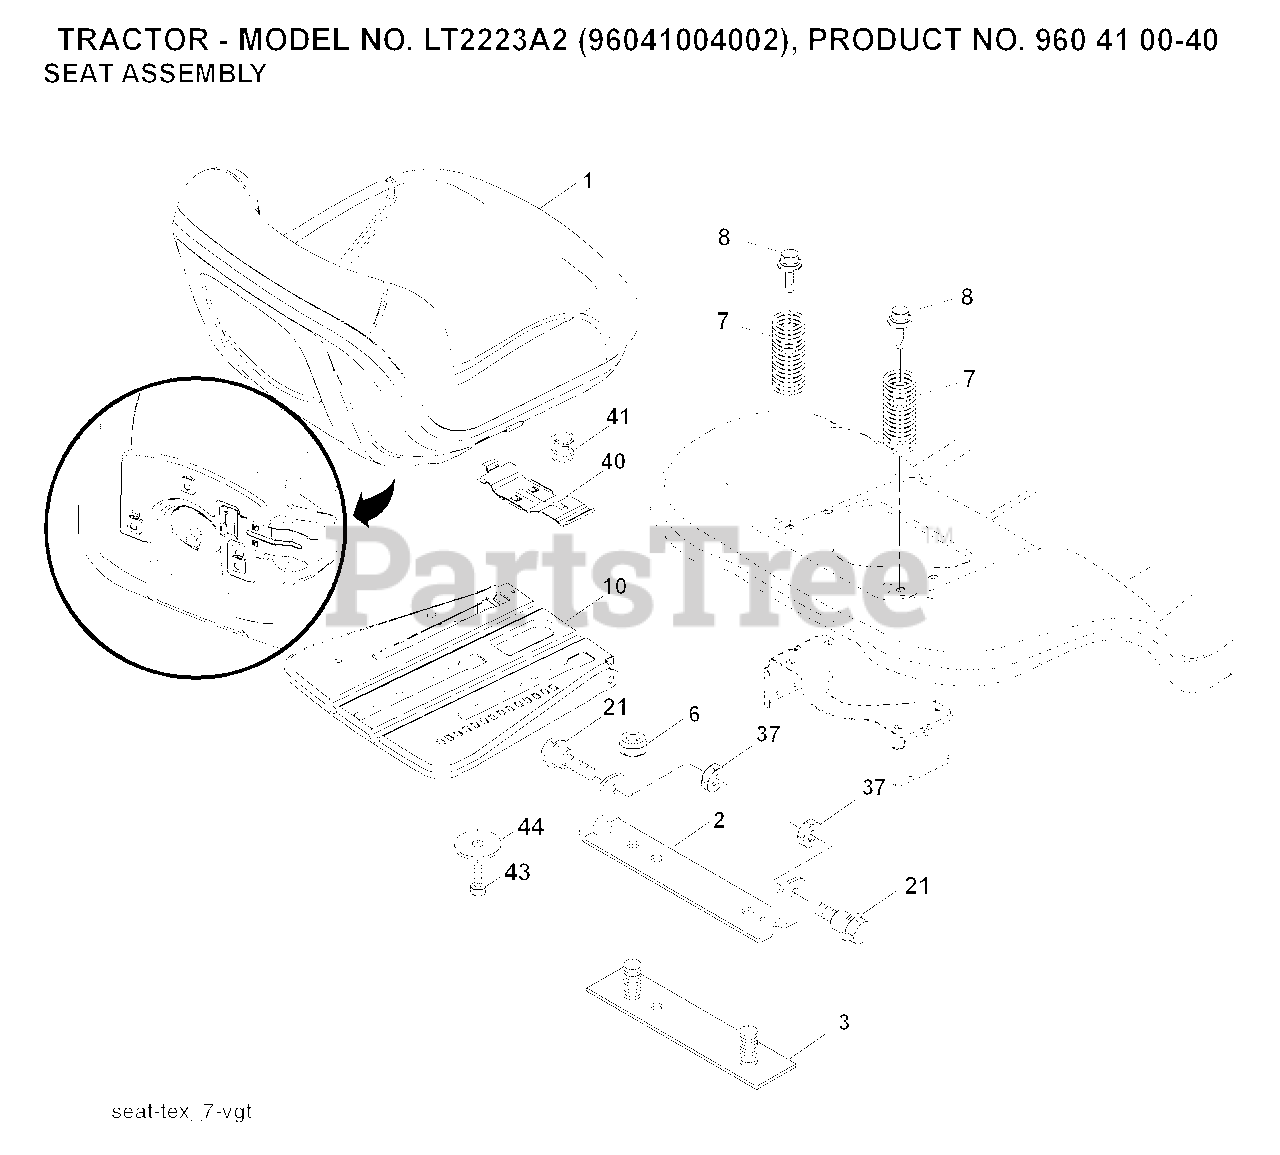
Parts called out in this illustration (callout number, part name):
1	SEAT.TG150.BLK.NLOGO.
2	BRKT.PIVOT.FENDER
6	NUT
7	SPRING COMPRESSION
8	BOLT, 5/16-18 X 1 3/4
10	PAN.ASM.SEAT.3PT
21	BOLT.SHOULDER.5/16-18
37	NUT.71038.31-18.HEX.NYLOCK
40	HANDLE.SLIDE.SEAT.TEX.BLACK
41	SPRING.LATCH.SEAT.TEX
44	WASHER 13/32 X 2-3/8 X 12GA
